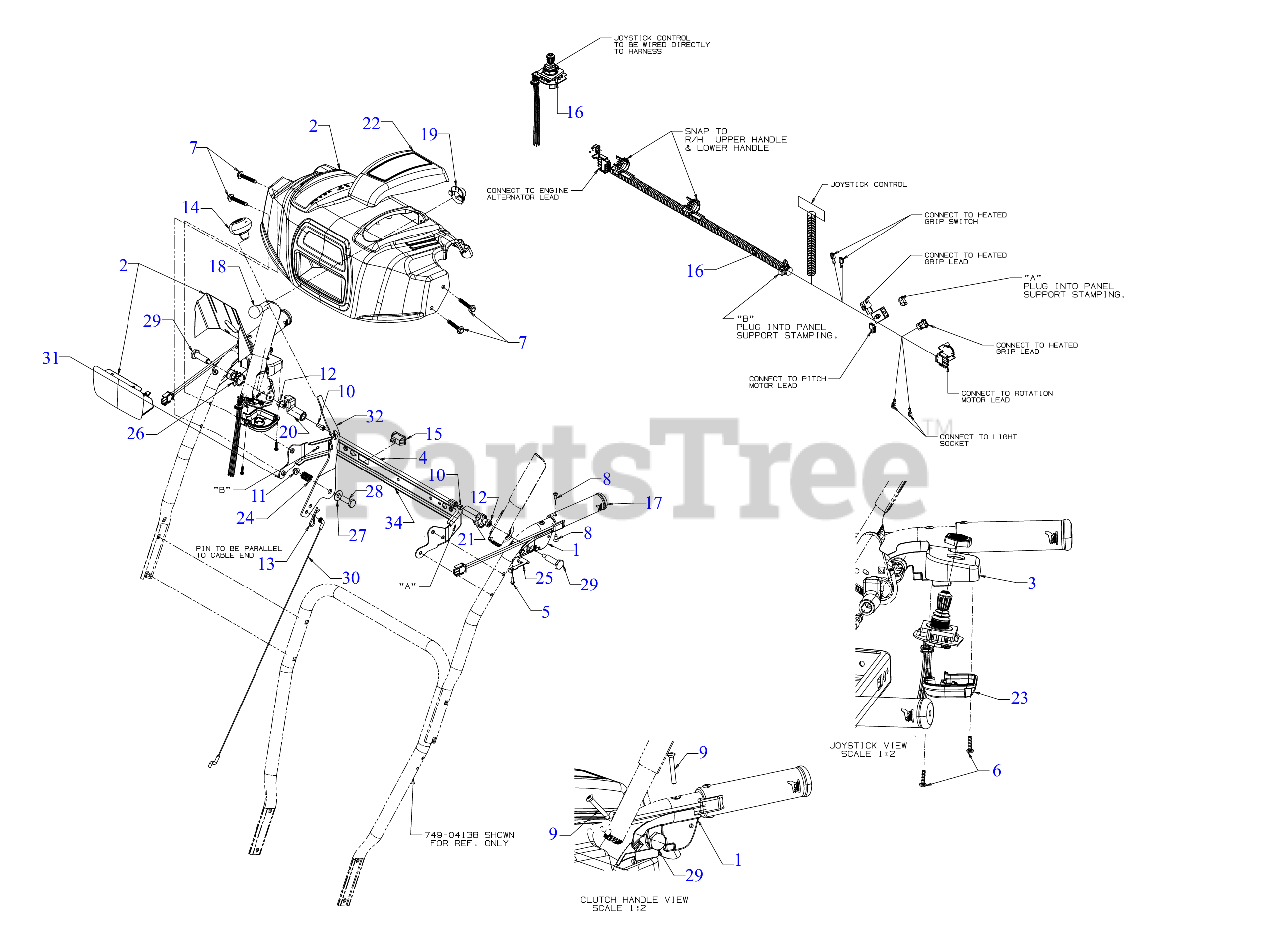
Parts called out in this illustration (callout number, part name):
1	CLUTCH LOCK HANDLE ASSEMBLY (LH)
2	HANDLE PANEL ASSEMBLY
3	CLUTCH HANDLE ASSEMBLY (RH)
4	PIVOT ROD
5	SCREW #8-16 x .50
6	SCREW .159 x .610
7	SCREW 1/4-20 x 1.625
8	SCREW #10-16 x .625
9	SCREW #10-24 x 1.375
10	SCREW 1/4-20 x .50
11	FLANGE LOCK NUT
12	HEX NUT W/PATCH
13	INTERNAL COTTER PIN
14	SHIFT KNOB
15	HEATED GRIP SWITCH
16	4-WAY ELEC/HEAT GRIP HARNESS
17	HARNESS-SNOW HEATED GRIP RED
18	LAMP-12 VOLT
19	HEADLIGHT SOCKET
20	LOCK PLATE
21	CLUTCH LOCK CAM
22	HANDLE COVER PANEL
23	JOYSTICK HOUSING COVER
24	COMPRESSION SPRING
25	CLUTCH SPRING
26	TORSION SPRING
27	FLAT WASHER .40X.88X.060
28	SHOULDER SCREW
29	SHOULDER SCREW .437 x 1.345 1/4-20
30	SPEED SELECTOR CABLE (PLASTIC)
31	HANDLE SUPPORT BRACKET (POWDER BLACK)
32	SHIFT LEVER
